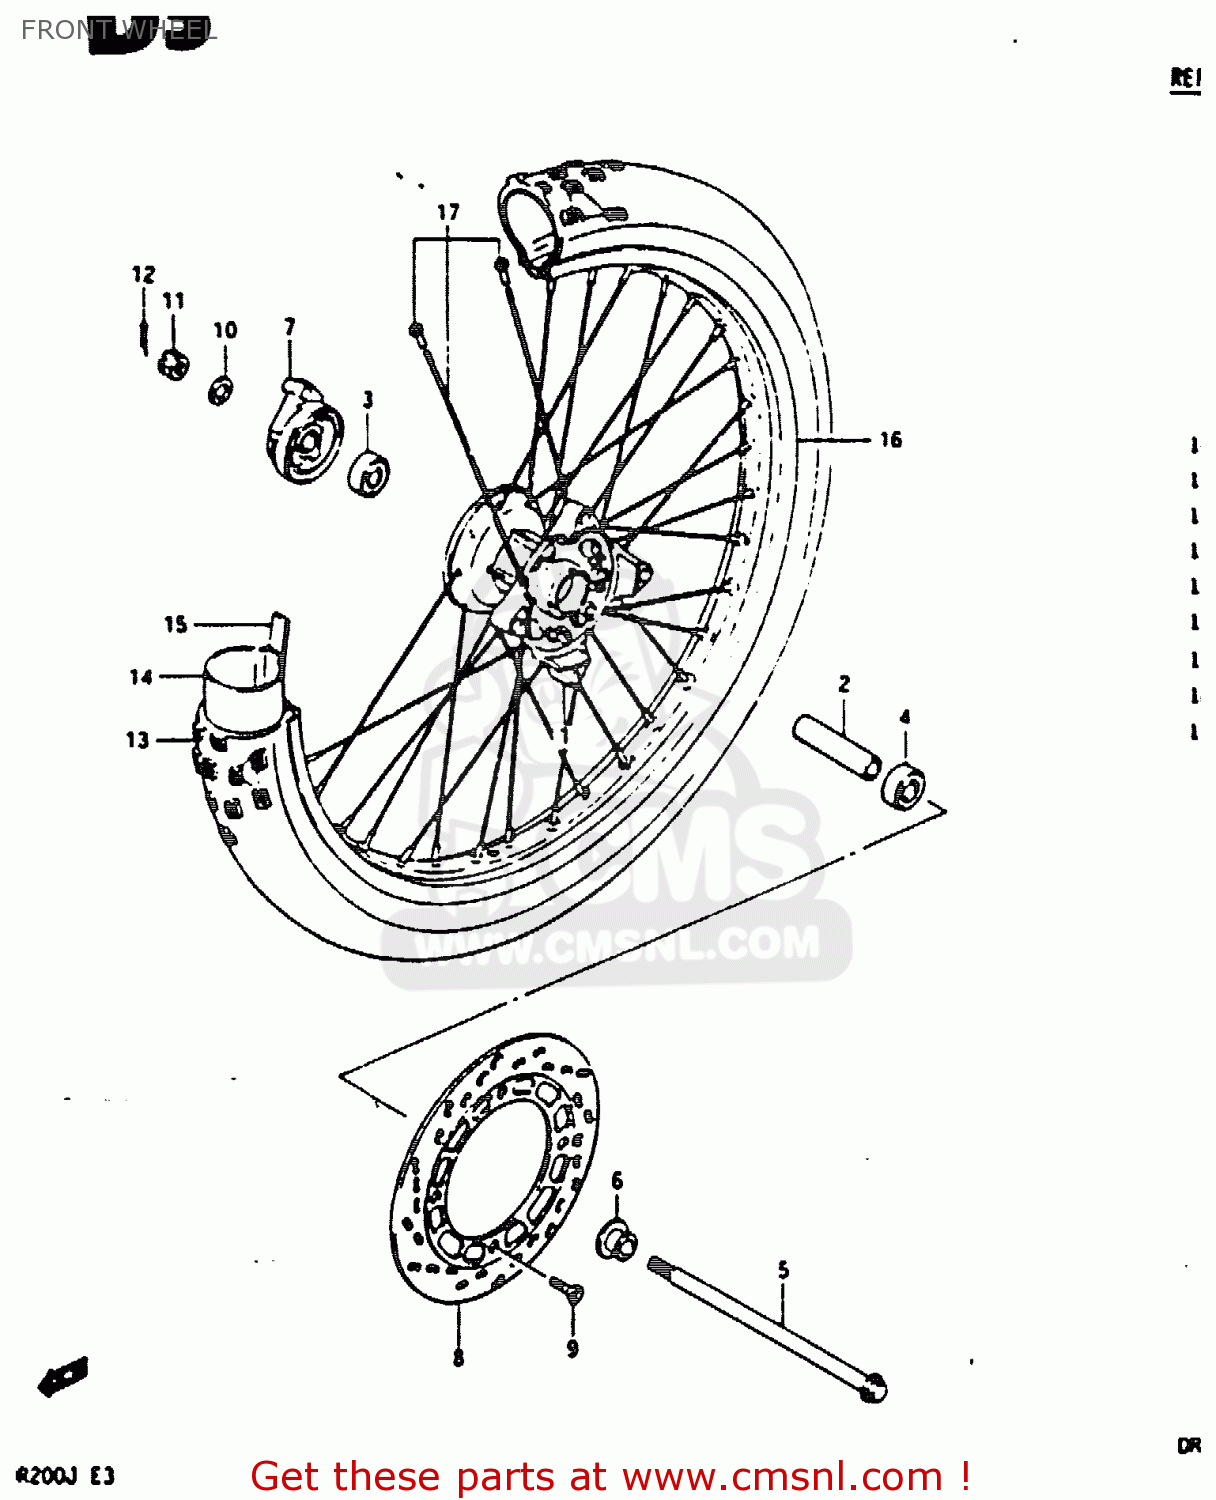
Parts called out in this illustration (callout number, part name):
1	HUB,FRONT
2	SPACER (12.6X19X60.5)
3	BEARING
4	BEARING (12X32X10)
5	AXLE,FRONT
6	SPACER,FRONT AXLE,RIGHT
7	BOX ASSY,SPEEDOMETER GEAR
8	DISC,BRAKE
9	BOLT,BRAKE DISC
10	WASHER
11	NUT 12MM
12	COTTER PIN
13	TIRE,FRONT 70/100-21
14	TUBE
15	PROTECTOR,WHEEL,INNER
16	RIM,FRONT WHEEL
17	SPOKE SET,FR WHEEL
